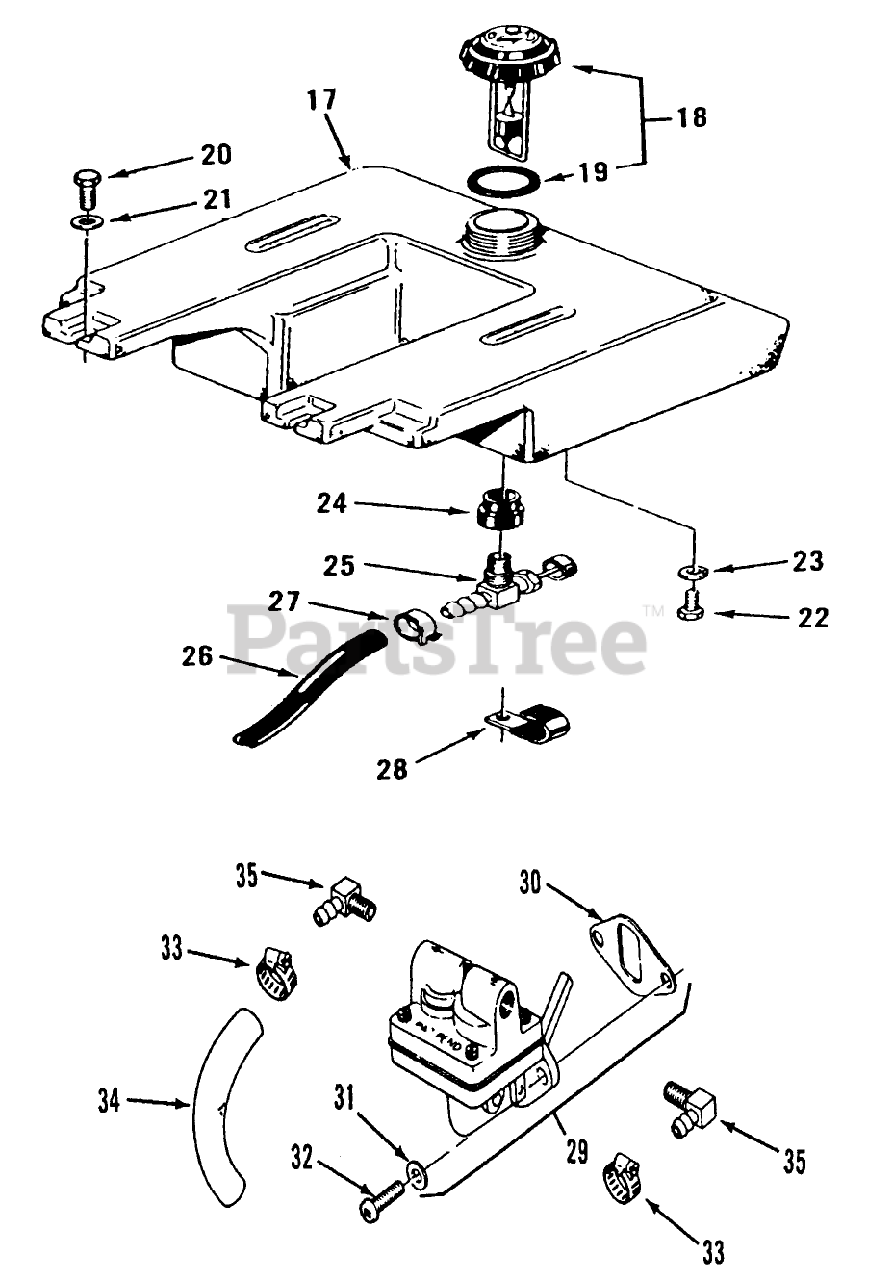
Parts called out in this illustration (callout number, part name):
17	TANK-FUEL
18	ASSY-GAUGE CAP
25	VALVE-FUEL
29	Fuel Pump Assy (Includes items 30 31)
30	Gasket-Fuel Pump
31	Washer
32	Screw-F.H.
33	Clamp
34	Line-Fuel
35	Connector
